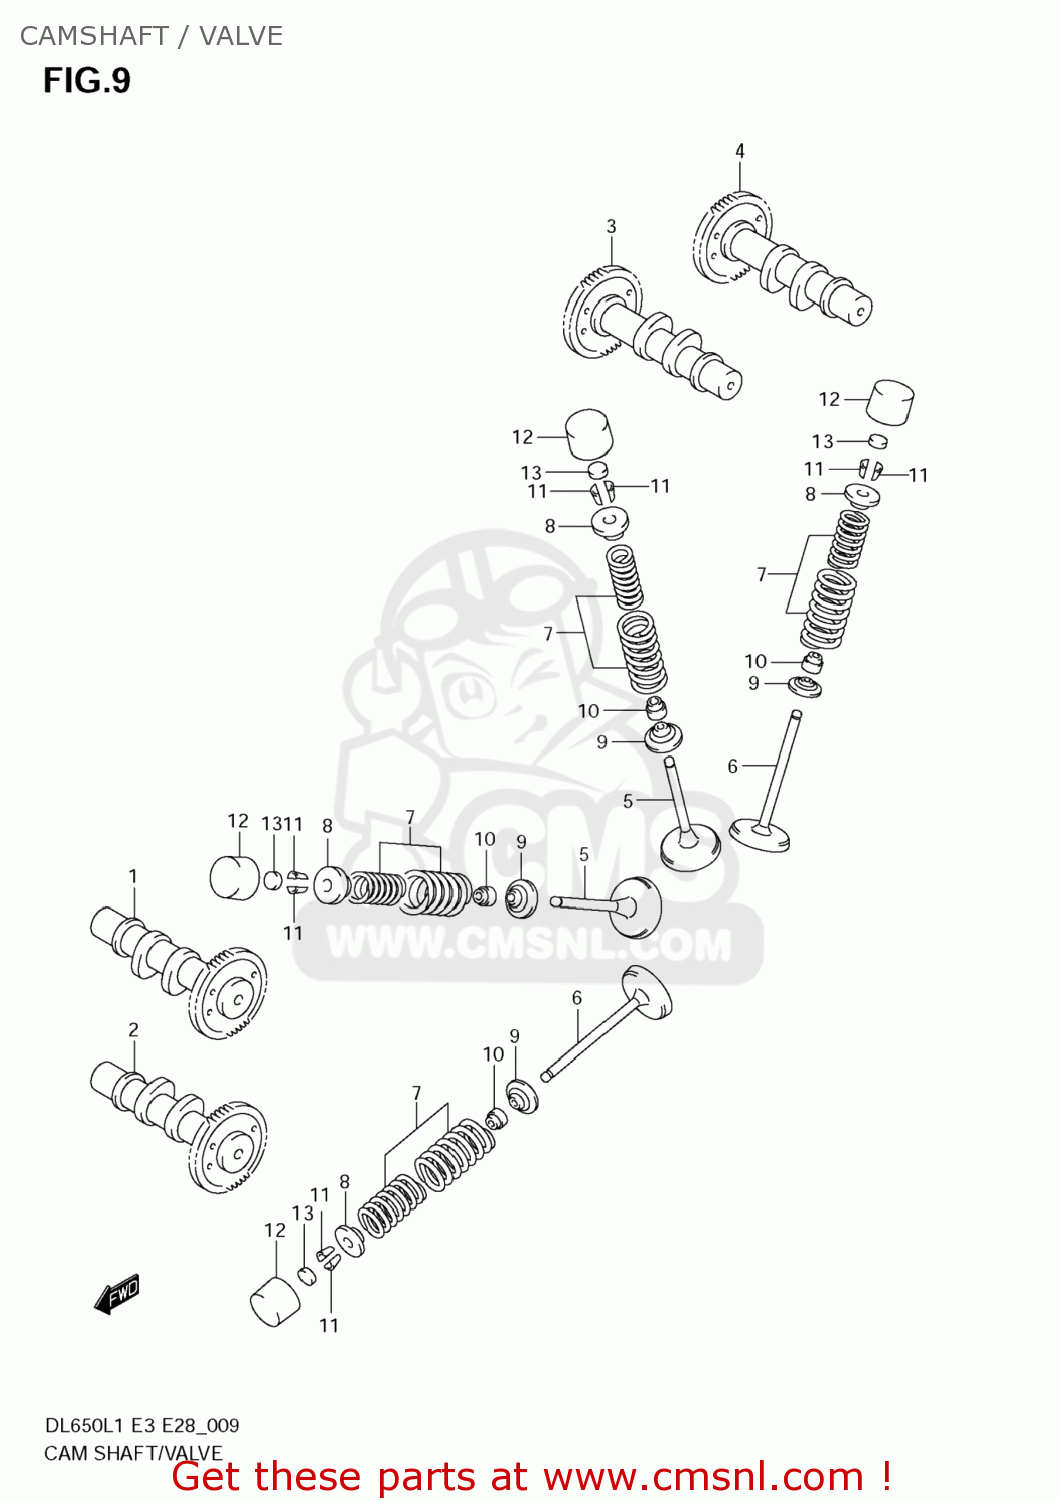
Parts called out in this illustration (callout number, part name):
1	CAMSHAFT,INTAKE FR
2	CAMSHAFT,EXHAUST FR
3	CAMSHAFT,INTAKE RR
4	CAMSHAFT,EXHAUST RR
5	VALVE,INTAKE
6	VALVE,EXHAUST
7	SPRING SET,VALVE
8	RETAINER,VALVE SPRING
9	SEAT,VALVE SPRING
10	SEAL,OIL(4.5X10X8)
11	COTTER VALVE
12	TAPPET
13	SHIM,TAPPET
14	SHIM SET,TAPPET
15	CASE,TAPPET SHIM
